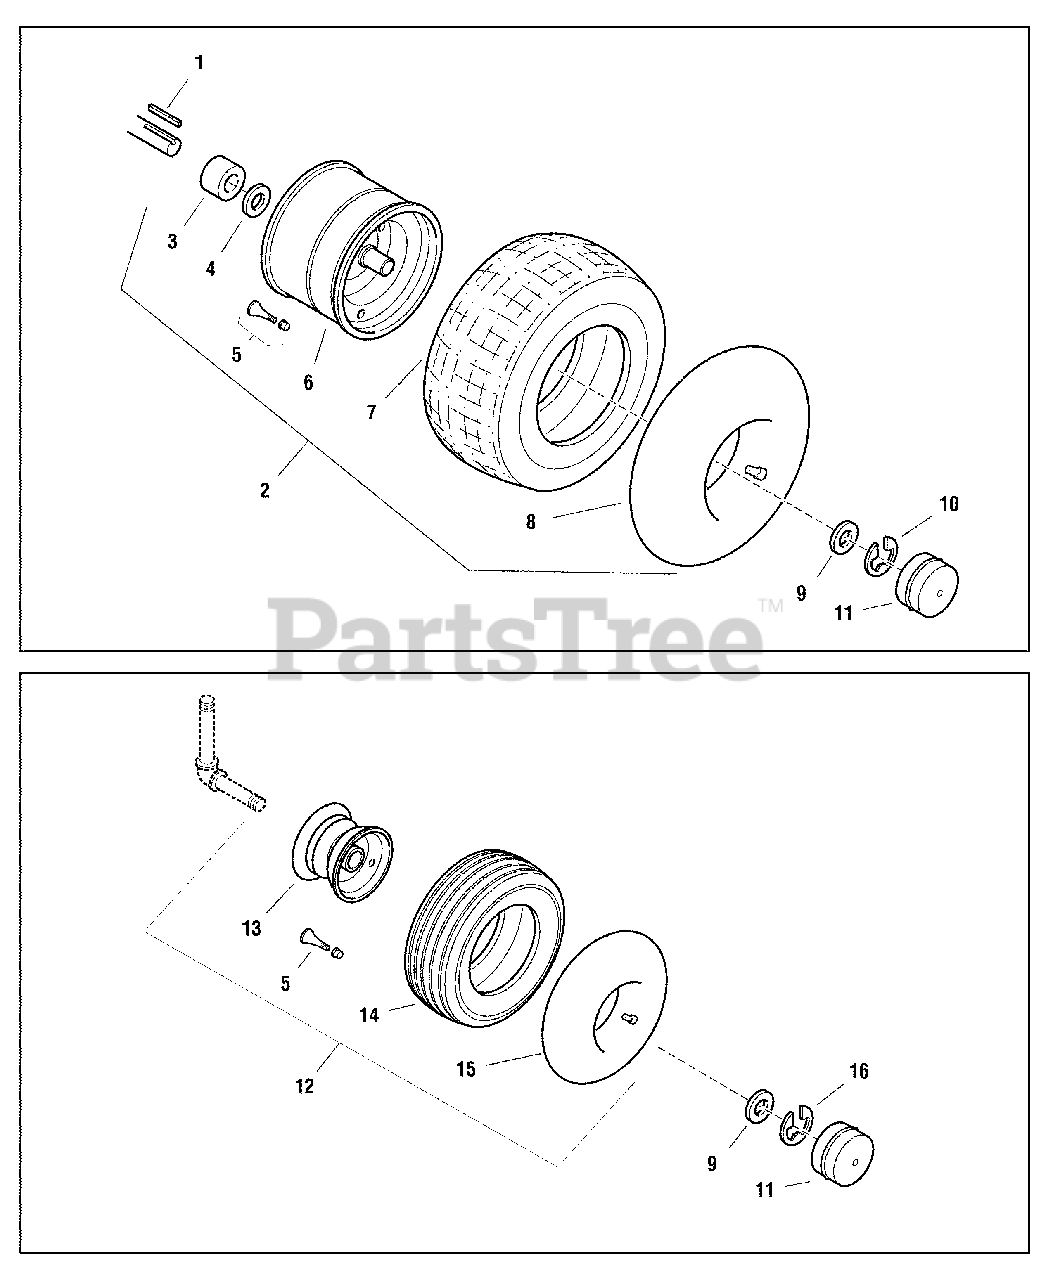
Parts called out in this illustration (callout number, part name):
1	KEY, Square, 3/16 x 3/16 x 1-1/2 long
2	REAR WHEEL & TIRE ASSEMBLY, Hoosier, (Includes Ref. Nos. 3, 4, 7 & 8)
4	WASHER, 3/4
5	VALVE STEM & CAP
6	REAR WHEEL ASSEMBLY, Metallic Gray
7	TIRE, Rear Wheel, 16 X 6.50-8
8	TUBE, Rear Wheel
9	WASHER, 3/4
11	HUB CAP, Silver
12	FRONT WHEEL & TIRE ASSEMBLY, Hoosier, 13 x 5.00-6, Metallic Gray (Includes Ref. Nos. 4, 15, 18 & 19)
13	FRONT WHEEL ASSEMBLY 13 x 5.00-6, Metallic Gray (Includes Ref. No. 16)
14	TIRE, Front Wheel, 13 x 5.00-6
15	TUBE, Front Wheel, 4.10/3.50 x 6
16	KLIP RING
